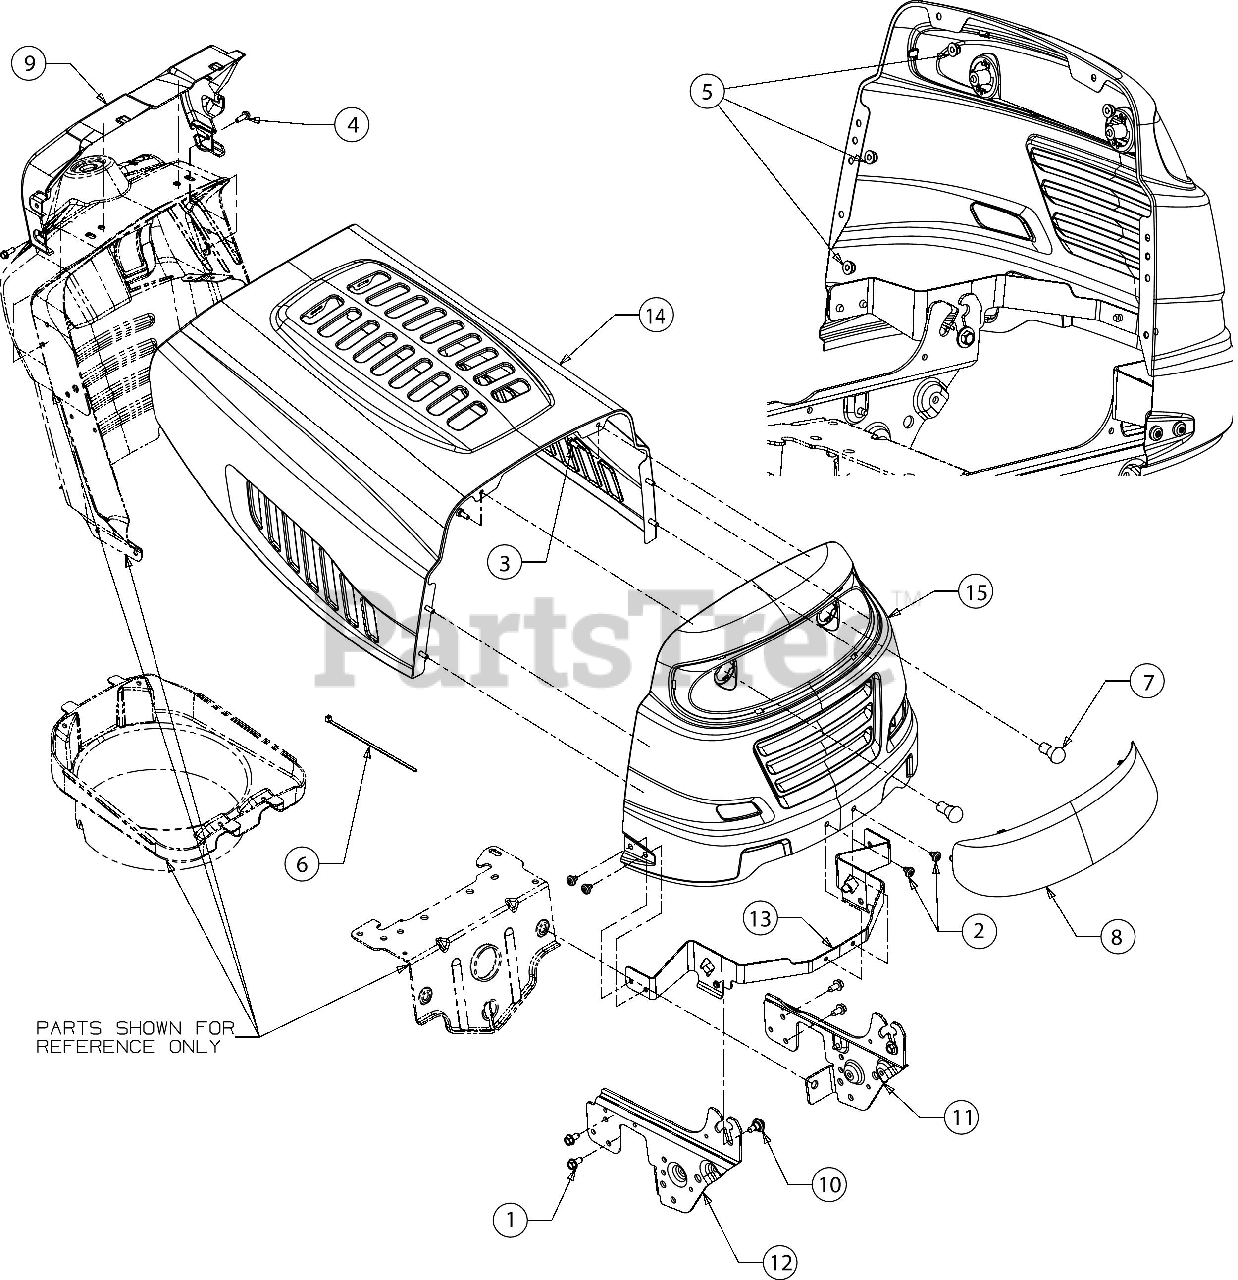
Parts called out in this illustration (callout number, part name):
1	SCREW 5/16-18 x .750
2	SCREW 5/16-18 x .375
3	SCREW 1/4-20 x .620 GR5
4	SCREW 1/4-15 x .750
5	FLANGE LOCK NUT
6	7" CABLE TIE
7	MINIATURE LAMP-12V #1156
8	GRILL LENS
9	DASH COLLAR
10	SHOULDER SCREW .43X.29X5/16-18 TT
11	SUPPORT BRACKET (LH)(POWDER BLACK)
12	PIVOT SUPPORT BRACKET (RH)(POWDER BLACK)
13	HOOD PIVOT BRACKET
